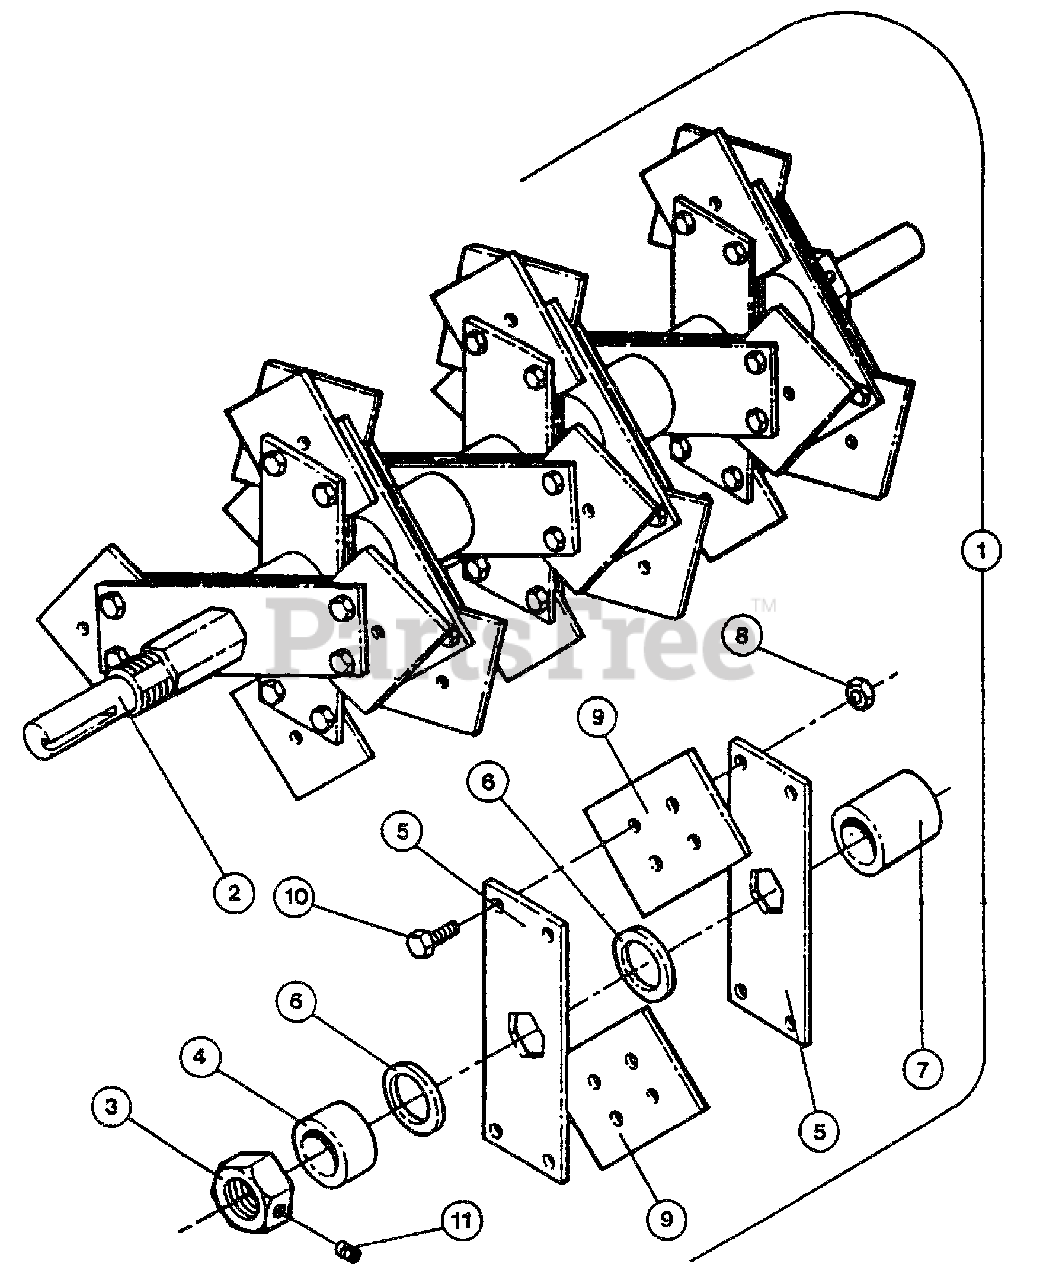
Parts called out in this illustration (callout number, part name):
1	Complete Slicer Shaft
2	Slicer Shaft, Bare
3	Jam Nut w/Set Screw
4	Sleeve Spacer (Short)
5	Blade Holder Plate
6	Blade Washer
7	Sleeve Spacer (Long)
8	1/4-20 Nyloc Nut
9	Slicer Blade
10	1/4-20 x 5/8 Hex Cap Screw
11	5/16-18 x 3/8 Set Screw
